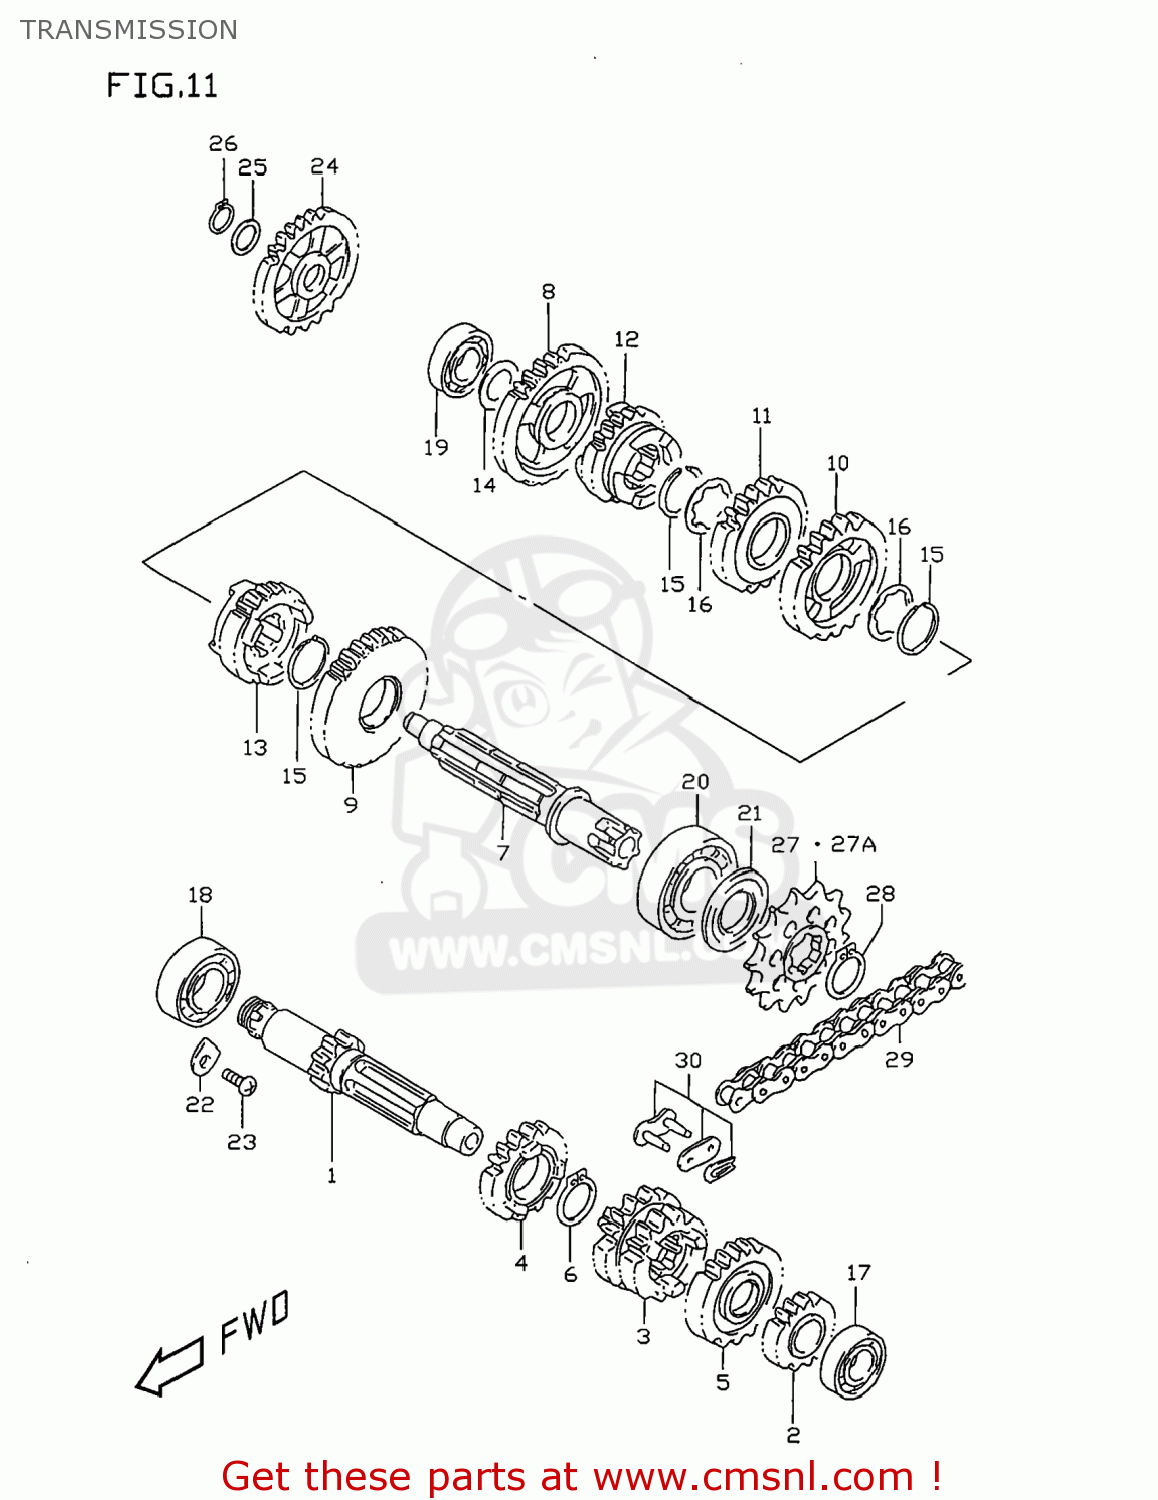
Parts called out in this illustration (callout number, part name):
1	SHAFT,COUNTER (NT:11)
2	GEAR,2ND DRIVE(NT:15)
3	GEAR,THIRD/FOURTH DRIVE
4	GEAR,FIFTH DRIVE
5	GEAR,6TH DRIVE
6	CIRCLIP
7	SHAFT,DRIVE
8	GEAR,FIRST DRIVEN
9	GEAR,SECOND DRIVEN
10	GEAR,THIRD DRIVEN (NT:22)
11	GEAR,FOURTH DRIVEN (NT:20)
12	GEAR,FIFTH DRIVEN
13	GEAR,6TH DRIVEN(NT:23)
14	WASHER,THRUST
15	CIRCLIP
16	WASHER,LOCK
17	BEARING
18	BEARING(20X42X12)
19	BEARING
20	BEARING(20X47X14)
21	OIL SEAL (20X35X5)
22	RETAINER
23	SCREW
24	GEAR,KICK STARTER IDLE(NT:24)
25	SHIM
26	CIRCLIP,12 MM
27	SPROCKET,ENGINE(NT:14)
27A	SPROCKET,ENGINE(NT:13)
28	CIRCLIP
29	CHAIN,DRIVE(428G2X118L)
30	JOINT SET,CHAIN
